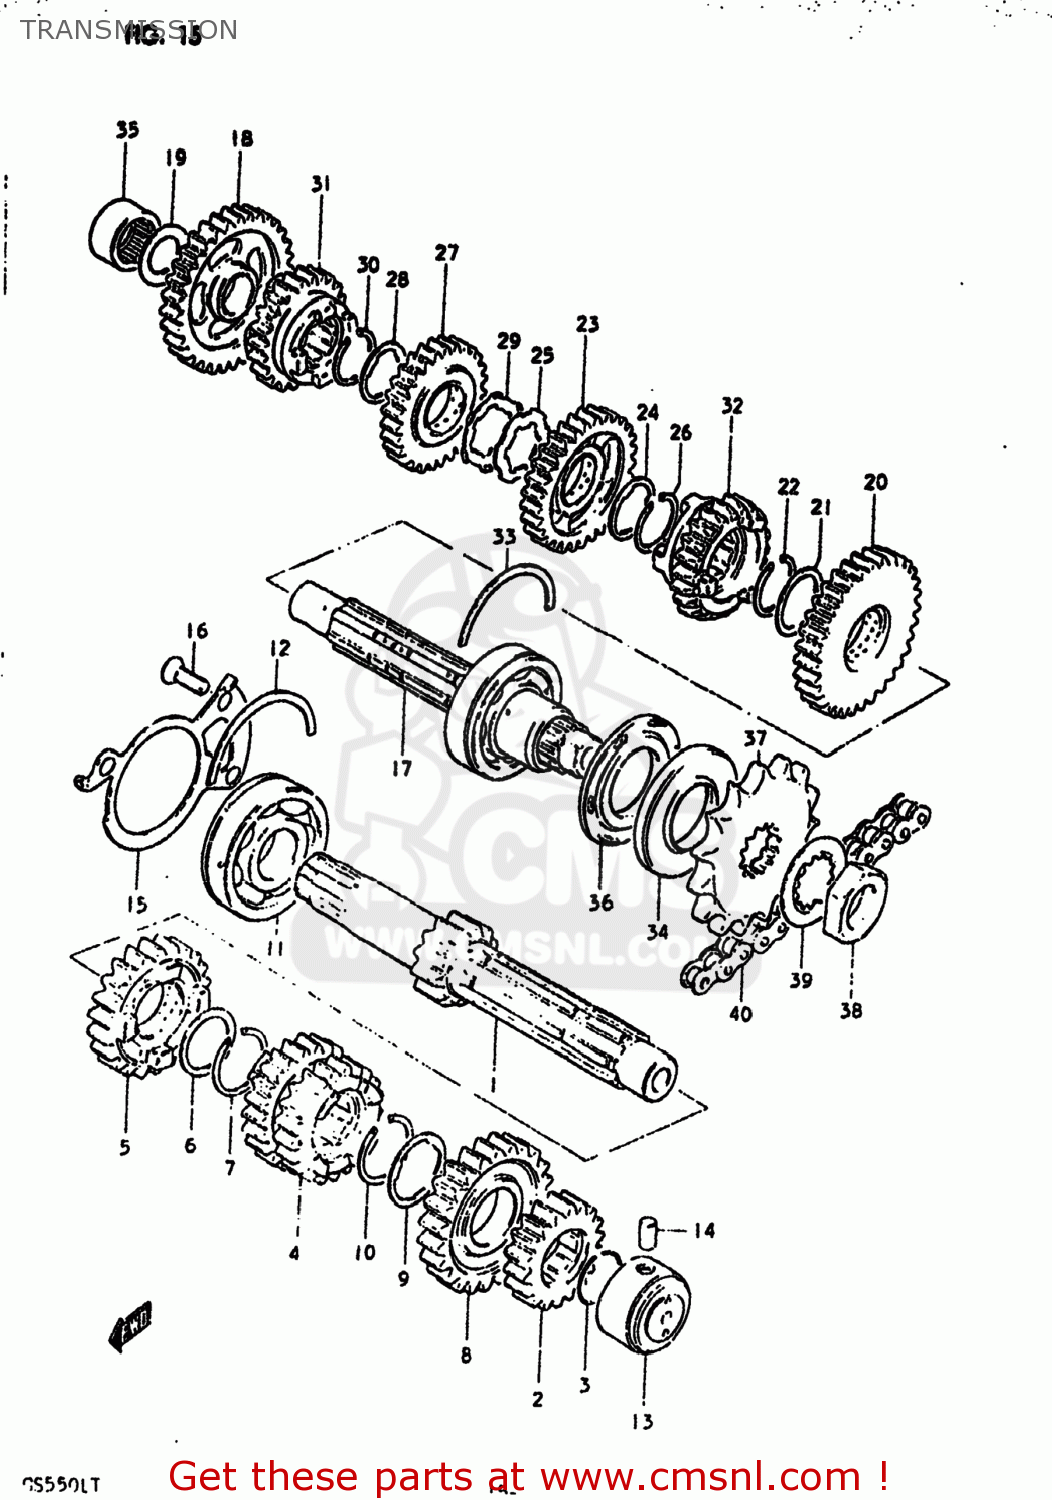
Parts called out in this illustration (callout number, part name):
1	SHAFT,COUNTER
2	GEAR,SECOND DRIVE
3	RING,SNAP
4	GEAR,THIRD DRIVE
5	GEAR,FIFTH DRIVE
6	WASHER
7	CIRCLIP
8	GEAR,SIXTH DRIVE
9	WASHER,LOCK
10	CIRCLIP
11	BEARING(25X62X17)
12	C-RING
13	BEARING
14	PIN
15	PLATE,COUNTERSHAFT BEARING
16	SCREW
17	SHAFT,DRIVE
18	GEAR,FIRST DRIVEN
19	WASHER
20	GEAR,SECOND DRIVEN
21	WASHER
22	CIRCLIP
23	GEAR,THIRD DRIVEN
24	WASHER,LOCK
25	WASHER,LOCK
26	CIRCLIP
27	GEAR,FOURTH DRIVEN
28	WASHER,LOCK
29	WASHER
30	CIRCLIP
31	GEAR,FIFTH DRIVEN
32	GEAR,SIXTH DRIVEN
33	C-RING
34	OIL SEAL
35	ROLLER BEARING (20X34X1
36	SEAL,OIL(32X62X5.5)
37	SPROCKET,ENGINE
38	NUT
39	WASHER
40	CHAIN ASSEMBLY,DRIVE
